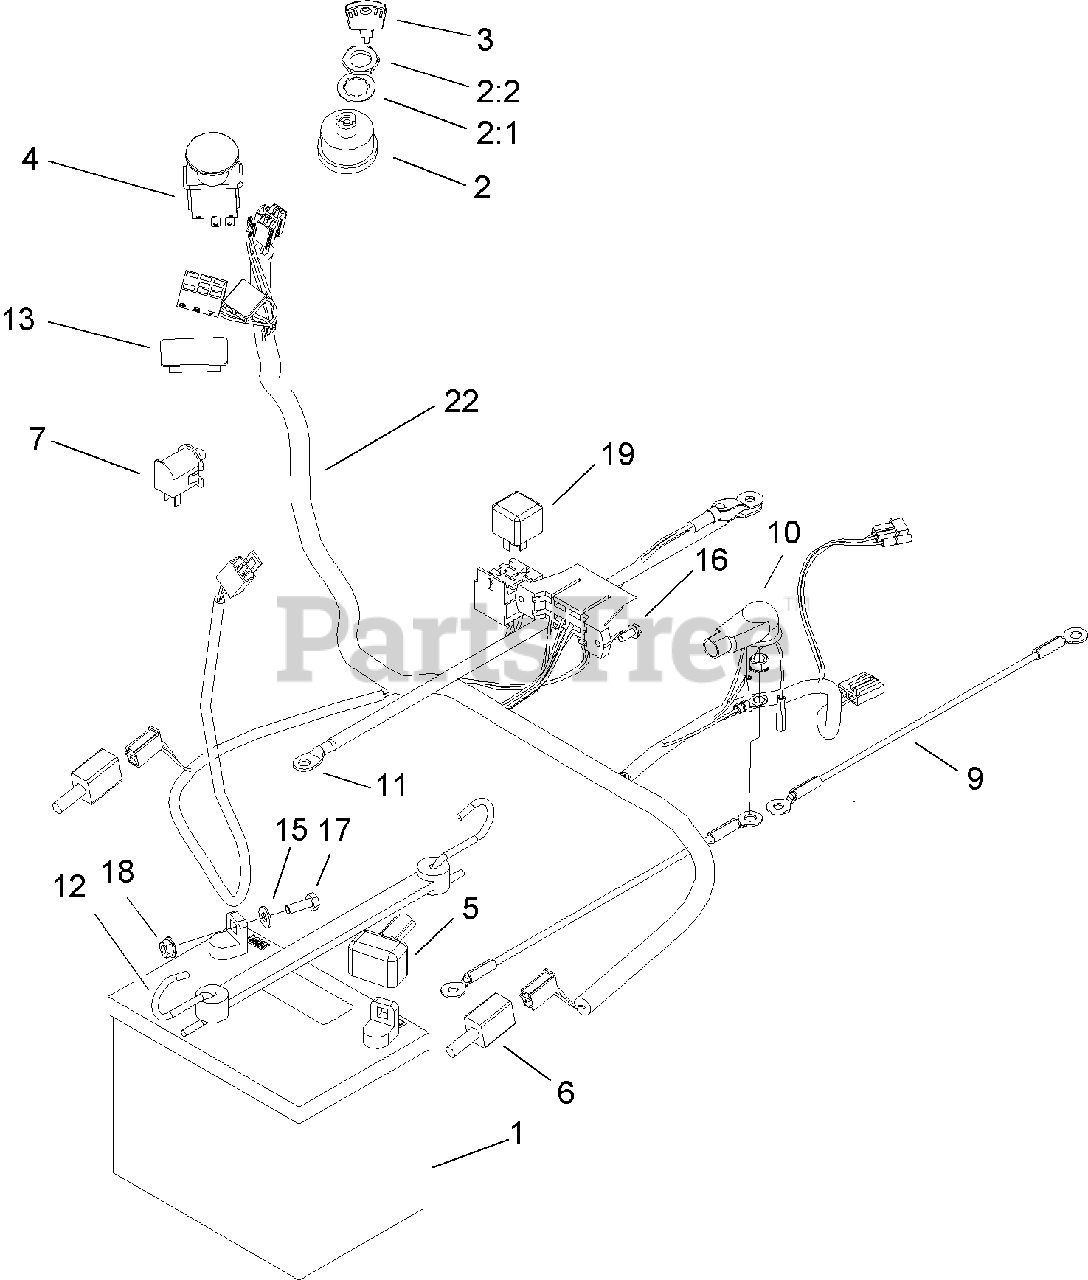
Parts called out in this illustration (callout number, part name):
1	BATTERY-DRY
2	Key Switch ASM
2:1	WASHER-TOOTH
4	SWITCH-PTO
5	BOOT-TERMINAL
7	SWITCH-BAIL
9	WIRE ASM
10	BOOT-INSULATOR, TERMINAL
12	HOLDDOWN-BATTERY
15	WASHER-FLAT
16	SCREW-TAPTITE
17	SCREW-HH
22	HARNESS-WIRE W/LIGHTS
